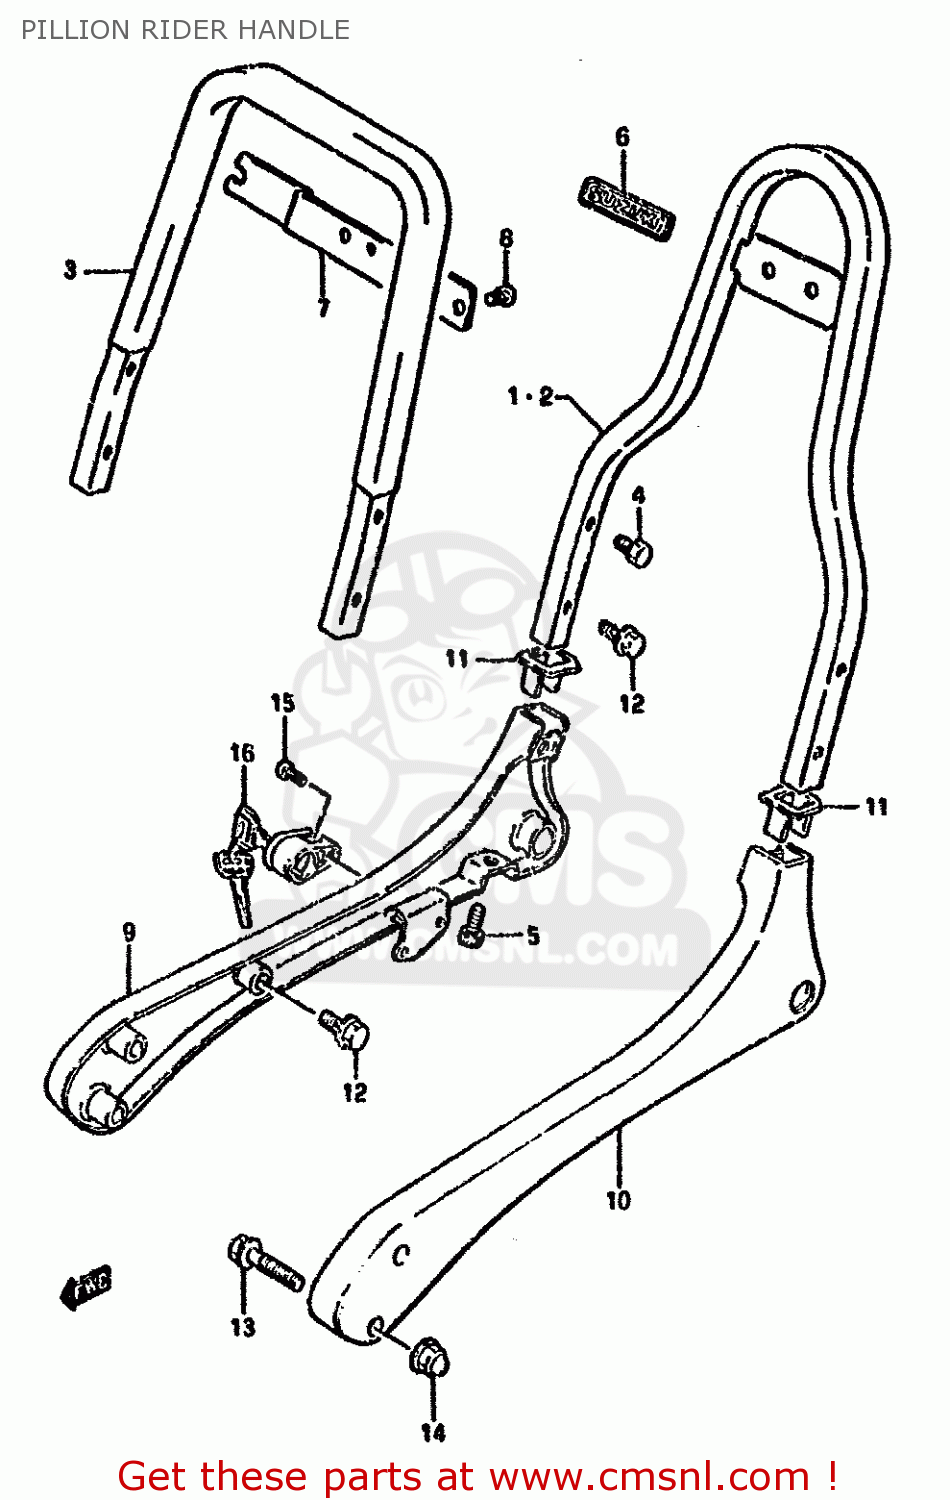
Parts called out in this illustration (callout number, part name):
1	HANDLE,PILLION UPR
2	HANDLE,PILLION UPR
3	HANDLE,PILLION RIDER UPPER
4	BOLT
5	BOLT,LOWER
6	EMBLEM
7	PLATE,RR
8	SCREW
9	HANDLE,PILLION RIDER,R
10	HANDLE,PILLION RIDER,L
11	COVER,PILLION HNDL
12	BOLT
13	BOLT,FRONT
14	NUT 8MM
15	LOCK SET,HELMET
16	SCREW
